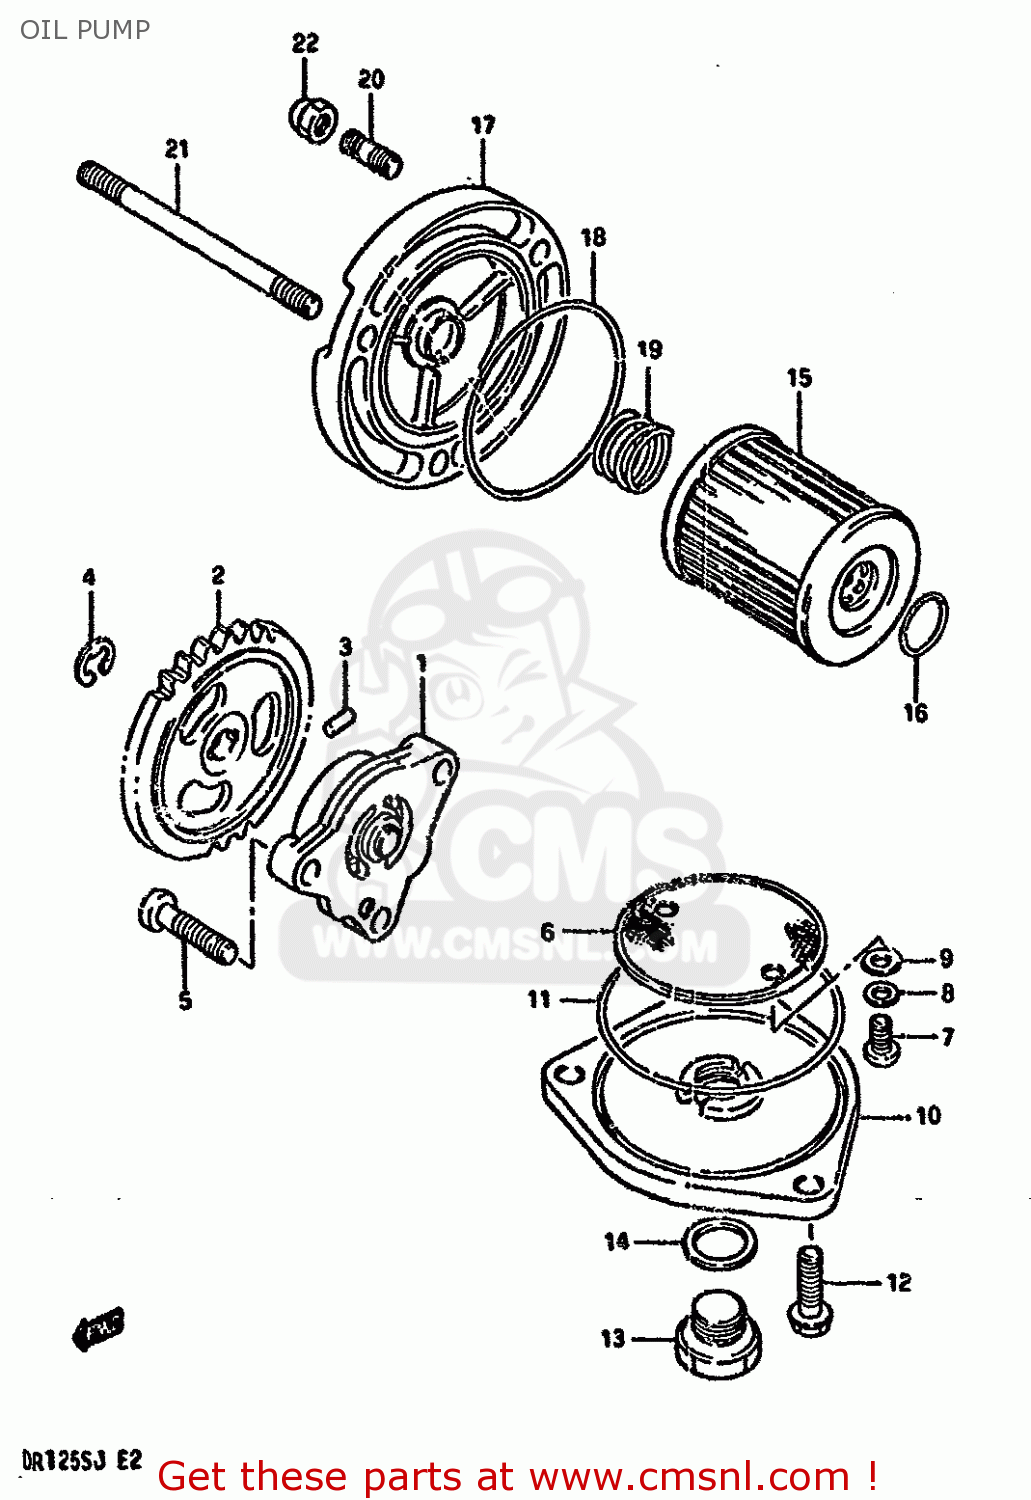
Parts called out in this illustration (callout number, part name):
1	PUMP ASSY,ENGINE OIL
2	GEAR,OIL PUMP DRIVEN (N
3	PIN(2.5X11.8)
4	E RING 6MM
5	SCREW
6	STRAINER,ENGINE OIL
7	SCREW 5X12
8	LOCK WASHER
9	WASHER
10	CAP,OIL STRAINER
11	O RING(D:2.4,ID:60.5)
12	BOLT
13	PLUG
14	GASKET(14X19.2X2) (NAS)
15	FILTER,OIL
16	O RING(D:1.9,ID:13)
17	CAP,OIL FILTER
18	O RING(D:2.4,ID:52.6)
19	SPRING
20	STUD 6X12
21	STUD BOLT
22	NUT 6MM
